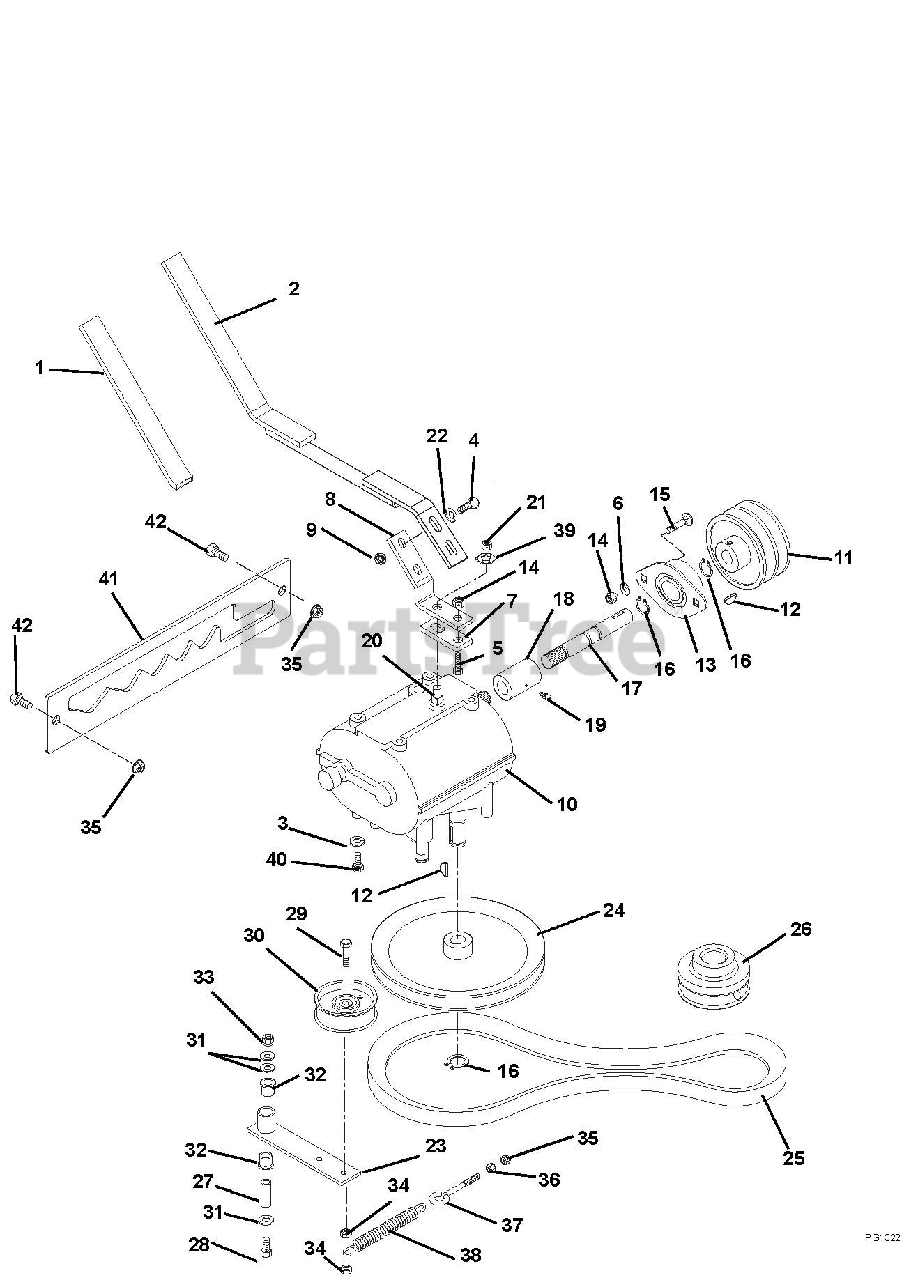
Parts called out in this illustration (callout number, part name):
1	Grip
2	Lever, Shift
3	Washer-Locking .31 x .078 Regular
4	Bolt-Hex .31-18 x 1.00 Grade 5
5	Bolt-Hex .25-20 x 1.00 Grade 5
6	Washer-Flat-Steel .25 x .562 x .049
7	Plate, Shift
8	Arm, Shift
9	Nut-Locking-Top-Flange .31-18
10	Transmission
11	Sheave, Drive
12	Key-Woodruff .19 x .75
13	Bearing-Flange .625 x 1.875 x .797
14	Nut-Locking-Nylon .25-20
15	Bolt-Round Head Square Neck .25-20 x .75 Grade 5
16	Ring-Retaining-External .579 x .930
17	Shaft, Half
19	Fitting, Lube, .25-28
21	Nut-Locking-Center .38-24
22	Washer-Flat-Steel .344 x .688 x .065
23	Weldment, Ground Drive Idler
24	Pulley-V 7.50 x .63 Sheave Transmission
25	V-Belt 4L-Section 33.9
26	Sheave, Clutch
27	Bushing, Steel .56 x .745 x 2.04
28	Bolt-Hex .50-13 x 3.25 Grade 5
29	Bolt-Hex .38-16 x 2.00 Grade 5
30	Idler-Pulley Flat 3.25 x .625
31	Washer-Flat-Steel .531 x 1.06 x .095
32	Bushing-Flange Nylon .762 x 1.00 x .58 x 1.48
33	Nut-Locking-Nylon .50-13
34	Nut-Locking-Jam-Center .375-16
35	Nut-Locking-Nylon .38-16
36	Nut-Hex .38-16
37	Eye Bolt
38	Spring, Extension
39	Washer, Locking .38 x .13
40	Bolt-Hex .31-18 x .75 Grade 5
41	Plate, Shift Lever Detent
42	Bolt-Hex .38-10 x 1.00 Grade 5
